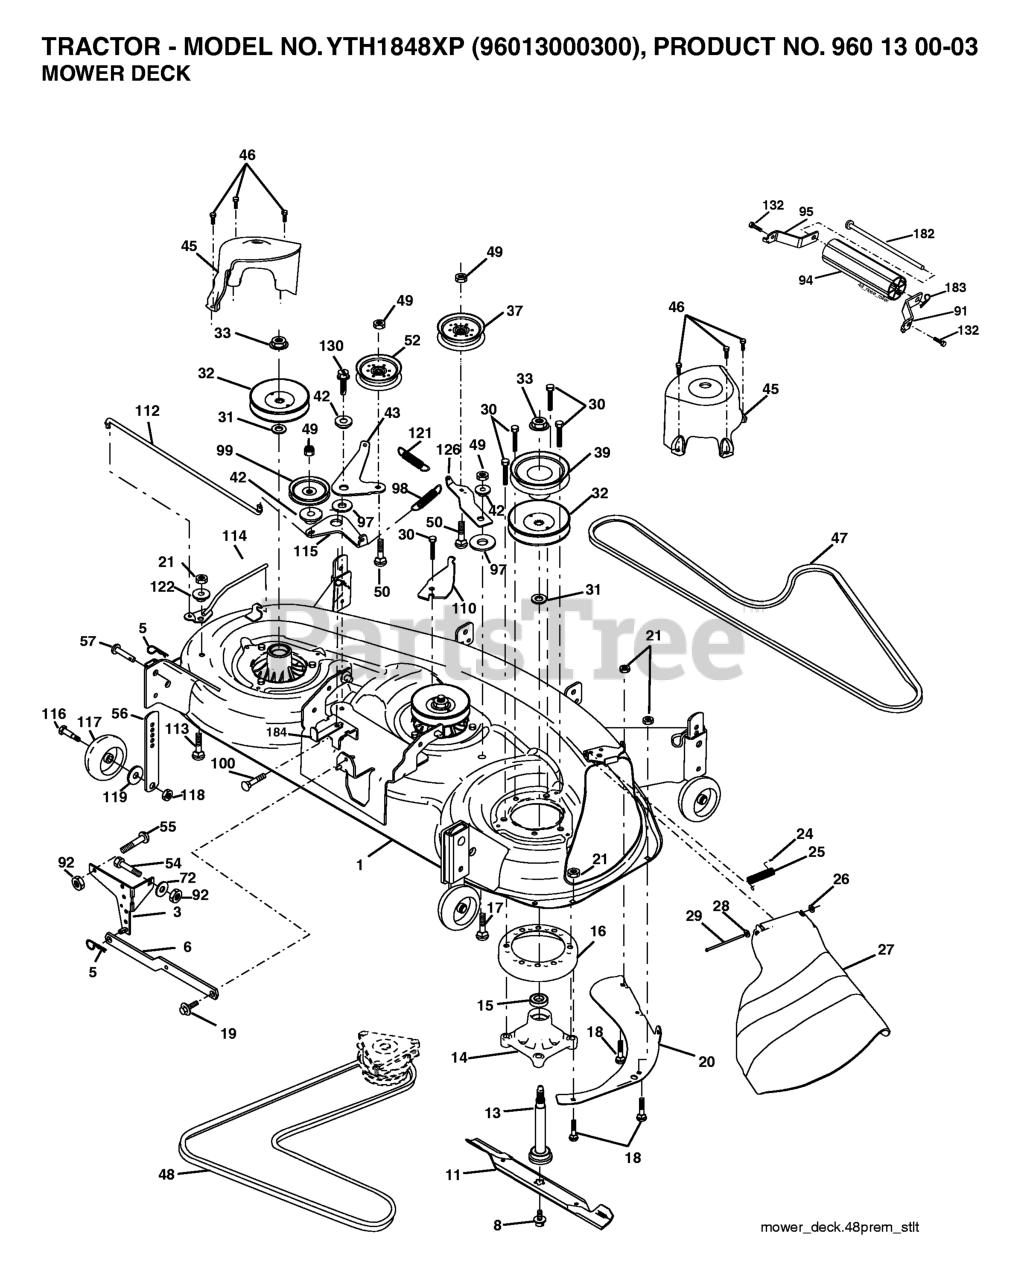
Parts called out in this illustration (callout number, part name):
1	DECK WELDMENT MOWER, 48
3	BRKT ASM SWAY BAR
5	RETAINER-SPRNG RB
6	BAR SWAY DECK
8	BOLT 7/16 ASM BLADE
11	48" HI-LIFT BLADE
13	SHAFT ASM W/LOWER BEARING
14	HOUSING, MANDREL 48"
16	STRIPPER.MANDREL.ROUND.BLACK
17	BOLT
18	BOLT
19	BOLT SHD 5/16-18
20	BAFFLE, VORTEX MWR
21	LOCKNUT
24	CAP-SLEEVE LT
25	SPRING, TORSION
26	NUT PUSH M
27	DEFLECTOR SUBS TO 532 180655
28	Washer 11/32 x 5/8 x 16 Ga SD
29	ROD.HINGE
30	SCREW, WASHER HEAD
31	WASHER.SPACER.MANDREL
32	PULLEY MANDREL
33	NUT, FLG TOPLOCK 9/16"
37	PULLEY.IDLER.FLAT
39	PULLEY.DRIVEN.DECK.48'
42	SPACER RETAINER
43	ARM, IDLER SECONDARY
45	COVER.MANDREL.DECK.48"
46	SCREW.1/4-20X5/8
47	V-BELT, 48"SECONDARY
48	V-BELT PRIMARY 48"
49	NUT LOCK FLG 3/8-16 UNC
50	BOLT.3/8-16X1.50
52	PULLEY.IDLER.FLAT.46.PR.DR.
55	BOLT D
56	BAR.ADJUST.WHEEL.ANTI.SCALP.BL
57	RIVET.PIN.HEAD.YELLOW.
72	WASHER
91	BRKT.NOSEROLLER.RH.48"
92	NUT
94	NOSE ROLLER 48"
95	BRKT.NOSEROLLER.LH.48"
98	SPRING PRIMARY DRIVE
99	RP PULLEY.V.IDLER.
110	ARM, SPRING SECONDARY
112	LEVER, TENSION RELIEF LINK
113	BOLT.CARR.SQNK.5/16-18UNC.X3/4
114	LEVER ASM, TENSION RELIEF
115	ARM, SPRING TENSION RELIEF
116	BOLT.SHOULDER.3/8-16X3-5/8.
117	RP WHEEL. GUAGE RALLY
118	LOCKNUT
119	WASHER.5/16.FLAT.STE.STD.
121	SPRING.DRIVE.SECONDARY.48".DEC
122	BUSHING, PIVOT TENSION RELIEF
126	ARM, IDLER PRIMARY DECK
130	SCREW 3/8-16X1
132	SCREW, 3/8-16X3/4
182	ROD.ROLLER.NOSE.NARROW.48"
183	SPRING RETAINER
184	KEEPER BELT IDLER PLATED
